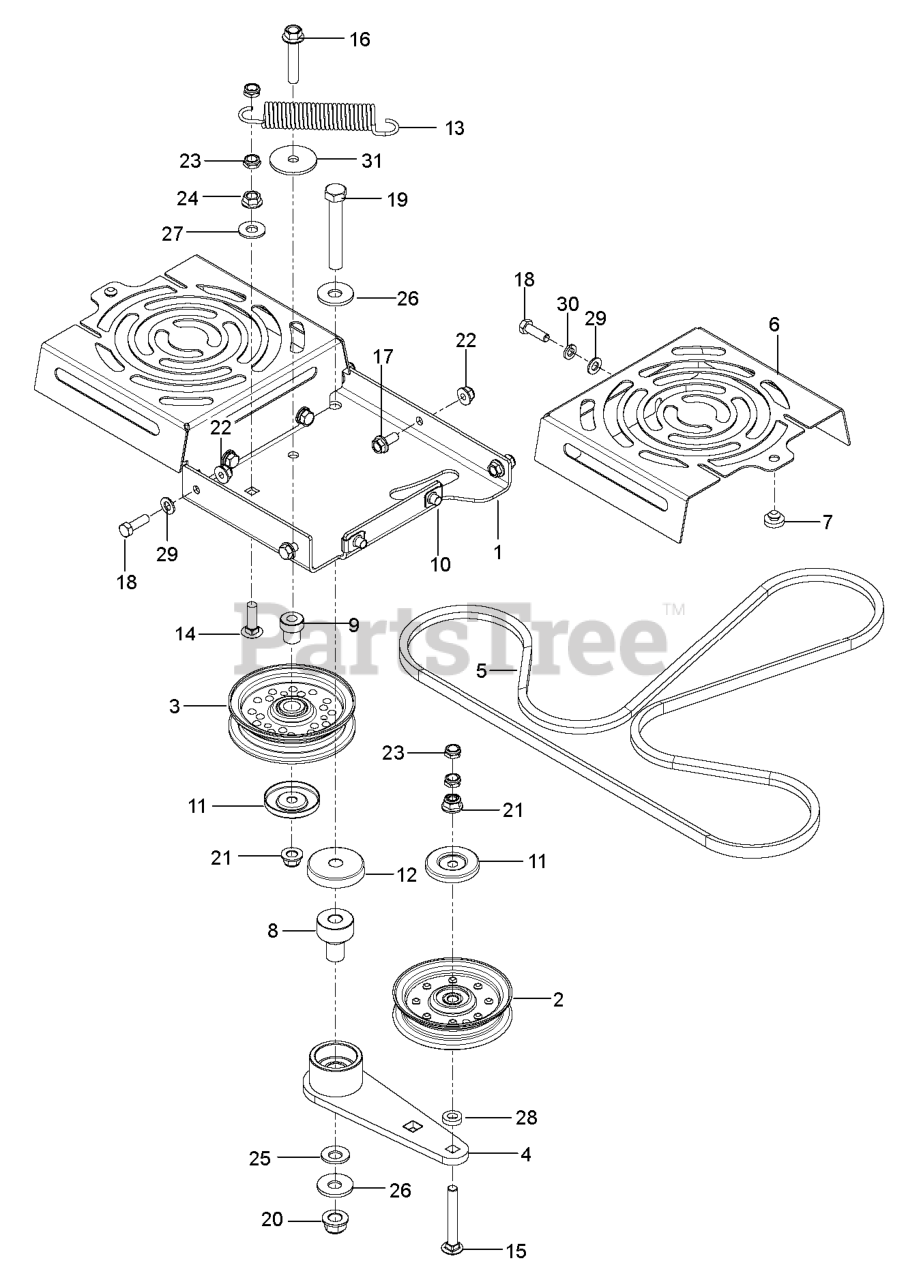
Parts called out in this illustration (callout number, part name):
1	PLATE.PNT.IDLER.SUPPORT.E-DIP
2	IDLER PULLEY
3	PULLEY.IDLER.FLAT.46.PR.DR.
4	ARM, IDLER, STEEL, W/BGS
5	BELT, HYDRO, 3400
6	SHIELD FAN BLACK
7	GROMMET, BUMPER
8	PIVOT, BEARING
9	PIVOT, IDLER
10	U-CLIP 5/16-18 NUT RETAINER
11	DUST SHIELD
12	SHIELD, DUST
13	SPRING, PUMP
14	BOLT.3/8-14X1.25
15	RHSNB 3/8-16 X 2.75
16	HHFS 3/8-16 X 2.0 GD 5
17	HHFS 5/16-18 X 3/4
18	HCS 5/16C X 1
19	HCS 1/2-13 X 3-1/4 GD 5 ZD
20	NUT, 1/2-13 HEX FLG NYLOC ZD
21	NUT 3/8-16 HEX FLG NYLOC ZD
22	5/16-18 NYLOC FLANGE NUT
23	NUT HEX 3/8-16 NYLON, THIN
24	NUT 3/8C WHIZ
25	CONTACT BELLSPR 1/2
26	WASHER.9/16 X 1 3/8 X 12 GA.
27	RP WASHER 3/8 FLAT
28	WASHER 3/8 X 3/4 X .187 TK
29	WASHER
30	WASHER.LOCK.HVY.HLCL.SPR.5/16
31	WASHER, 3/8 SPEC
